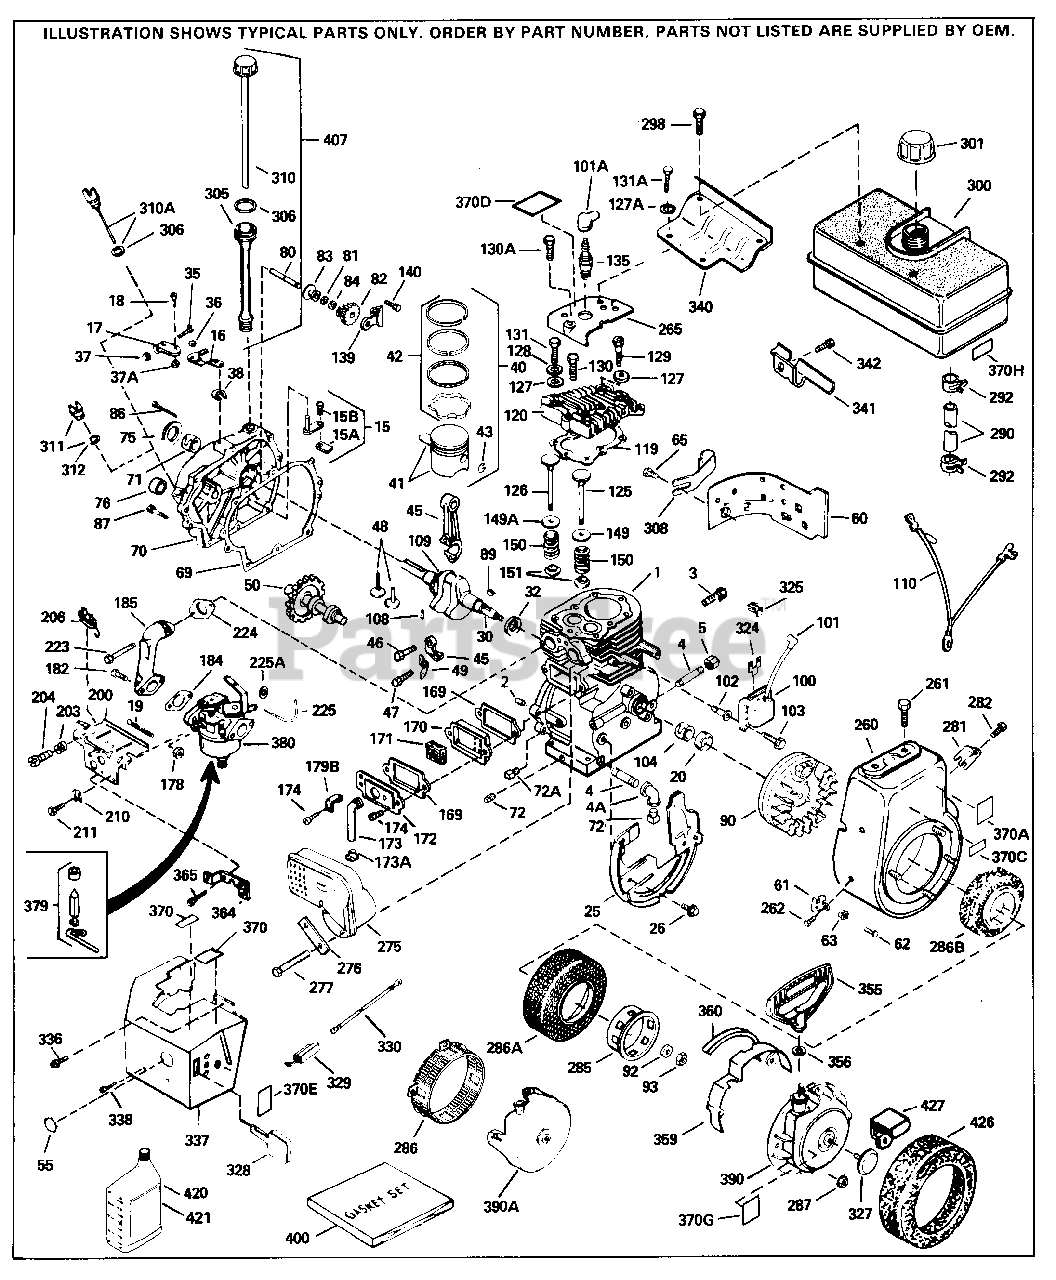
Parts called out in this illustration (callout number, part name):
1	"Cylinder Ass'y. (Incl. 2, 20, 72 & 72 A) (3-1/8" Bore) Bore)
2	Dowel Pin
15	Rod Assy., Governor (Incl. 15A & 15B)
15A	Yoke, Governor
15B	Screw, 6-40 x 5/16"
16	Governor Lever Assy.
17	Governor Lever Clamp
18	Screw, 8-32 x 5/16"
20	Oil Seal
25	Blower Housing Baffle
26	Screw, 1/4-20 x 5/8"
30	Crankshaft
32	Washer, Thrust
35	Screw, 10-32 x 3/4"
36	Lock Washer #8
37	Lock Nut, 10-32
37A	Lock Nut, 8-32
38	Retaining Ring
45	Connecting Rod Ass'y. (Incl.46,47,49)
46	Bolt, Connecting rod
47	Bolt, Connecting rod
48	Lifter, Valve
49	Oil Dipper
50	Camshaft (MCR)
60	Extension, Blower housing
65	Screw, 10-24 x 1/2"
69	* Gasket, Cylinder cover
70	Cyl. Cover Incl. 71,74,75,80,175,176, 311,312
72	Oil Drain Plug (Sq. hd., 1/4-18)
75	Seal, Oil
80	Shaft, Mechanical governor
81	Washer, Flat
82	Governor Gear Ass'y. (Incl. 81)
83	Spool, Governor
84	Retaining Ring
86	Screw, 1/4-20 x 1-3/16"
87	Screw, 1/4-20 x 1-11/16"
89	Key, Flywheel
90	Flywheel
92	Washer, Belleville
93	Nut, Hex (5/8-18) (Add-on alternator)
100	Solid State Ignition
101	Cover, Spark plug (Use as required)
102	Stud, Lamination mounting
103	Screw, Torx T-15, 10-24 x 1"
119	* Gasket, Head
120	Head, Cylinder
125	Exhaust Valve (Std.)(Incl. 151)
125	Exhaust Valve (1/32" OS) (Incl. 151)
126	Intake Valve (Std.) (Incl. 151)
126	Intake Valve (1/32" OS) (Incl. 151)
127	Washer Use as req., but not w/6021A s crew
127A	Washer, Flat (Use as required)
128	Washer, Belleville
129	Screw, 5/16-18 x 1-3/4" Use as requir ed
130	Screw, 5/16-18 x 2" (Use as required)
130A	Screw, 5/16-18 x 1-1/2" Use as requir ed, but do notuse with 650691 washer
131	Screw, 1/4-20 x 1/2" Use as required
131	Screw, 1/4-20 x 5/8" Use as required
131A	Screw, 5/16-18 x 5/8" Use as require d
131A	Screw, 5/16-18 x 7/8" Use as require d
135	Resistor Spark Plug - RJ17LM
139	Bracket, Governor gear
140	Screw, 10-24 x 1/2"
149	Valve Spring Cap
149A	Seal Assy., Intake valve
150	Valve Spring
151	Cap, Lower valve spring
169	* Gasket, Breather cover
170	Breather Body
171	Breather Element
172	Valve Cover
173	Breather Tube
174	Screw, 10-24 x 1/2"
174	Screw, 10-24 x 5/8"
178	Nut & Lock Washer 1/4-28
179B	Clip, Primer line (Use as required)
182	Screw, 1/4-28 x 1"
184	* Gasket, Carburetor
185	Pipe, Intake
206	Terminal Assy. (Use as required)
223	Screw, Torx T-30, 5/16-18 x 1-1/8 "
224	* Gasket, Intake pipe
260	Blower Housing (For electric starter)
261	Screw, 5/16-18 x 3/4" Use as require d
262	Screw, T-40, 5/16-24 x 21/32"
265	Cover, Cylinder head
275	Muffler
275C	Muffler (Optional quiet muffler)
276	Plate, Muffler locking
277	Screw, 5/16-18 x 3-3/16"
277A	Screw, 5/16-18x2-3/4" Used with 276A
281	Cover, Starter bubble
282	Screw, 8-32 x 3/8"
285	Cup, Starter
286A	Screen, Starter
287	Nut & Lock Washer 1/4-28
290	Fuel Line (8.62") req.)
290	Fuel Line (Braided 16")(41 cm) Use as req.
290	Fuel Line (Braided 32")(81 cm) Use as req.
292	Fuel Line Clamp
298	Screw, 1/4-15 x 7/8"
300	Fuel Tank (Incl. 292 & 301) NOTE: The se tanks were builtwith different siz e fuel inlet openings. Tanks with the 1-3/16" I.D. opening use fuel cap 34 210. Tanks with the 1-1/2" I.D. openi ng use fuel cap 35355.
301	Fuel Cap (Red 1-1/2" ID) (also availa ble in Packaged Part #740005B) (Red Plastic) (Spurt Resistant, Low Profil e) (1-3/16" I.D.)
301	Fuel Cap (Red Plastic) (Spurt Resista nt, High Profile) (1-3/16" I.D)
301	Fuel Cap (Red)
301	Fuel Cap (White Plastic)(Std) 1-1/2" I.D.
306	* Gasket, Oil fill
310A	Dipstick (Incl. 306)
325	Wire Clip
325	Clip, Ground wire (Use as required)
340	Plate, Fuel tank mounting
341	Bracket, Fuel tank mounting
342	Screw, 1/4-20 x 5/8"
370	Decal, Instruction
370A	Decal, Name
370J	Decal, Instruction Can be used on HM8 0 with diecast starter.
379	Inlet Needle, Seat & Clip Assy.
380	Carburetor (Incl. 184) (Refer to Divi sion 5, Section A, page 188 for break down or Fiche18A-1, Grid F-5)
390	Rewind Starter Refer to Division 5, S ection C, page 30 for breakdown or Fi che 18A-1, Grid G-5
400	Gasket Set (Incl. items marked*)
408	Screen Seal Can be used on HM80 with stamped steel recoil starter
409	Spacer Can be used on HM80 with stamp ed steel recoil starter
410	Debris Screen Kit (Incl. 360, 370B, 3 87, 411 &413) (Can be used on HM80 wi th stamped steel recoil starter)
411	Debris Screen Can be used on HM80 wit h stamped steel recoil starter
413	Screw, 5/16-18 x 1-5/8" Can be used o n HM80 with stamped steel recoil star ter
420	SAE 30, 4-Cycle Engine Oil (Quart)
421	SAE 5W30 4-Cycle Engine Oil - Quart - Winter
425	Starter Muff Kit (Incl. 370J, 426 & 4 27) (Can be used on HM80 with di e cast starter)
429	Screw, 8-18 x 1-1/8" (3 Required) (Us e as required) (Refer to Mechanics Ha ndbook for installation instructions) .
430	Alternator, Add on (Use as required) (Refer to Mechanics Handbook for inst allation instructions).
431	Centering tube (Use with engines equi pped with die cast aluminum starter)( Use as required) (Refer to Mechanics Handbook for installation instruction s)
431	Centering tube (Use as required) (Ref er to Mechanics Handbook for installa tion instructions).
432	A.C. Lighting Connector (Use as requi red) (Refer to Mechanics Handbook for installation instructions).
432	D.C. Charging Connector (Use as requi red) (Refer to Mechanics Handbook for installation instructions).
433	Alternator Shaft (4.00") (Use with en gines equipped with cast aluminum sta rter)(Use as required) (Refer to Mech anics Handbook for installation instr uctions).
433	Alternator Shaft (Use with engines e quipped with stamped steel starter)(U se as required) (Refer to Mechanics H andbook for installation instructions ).
